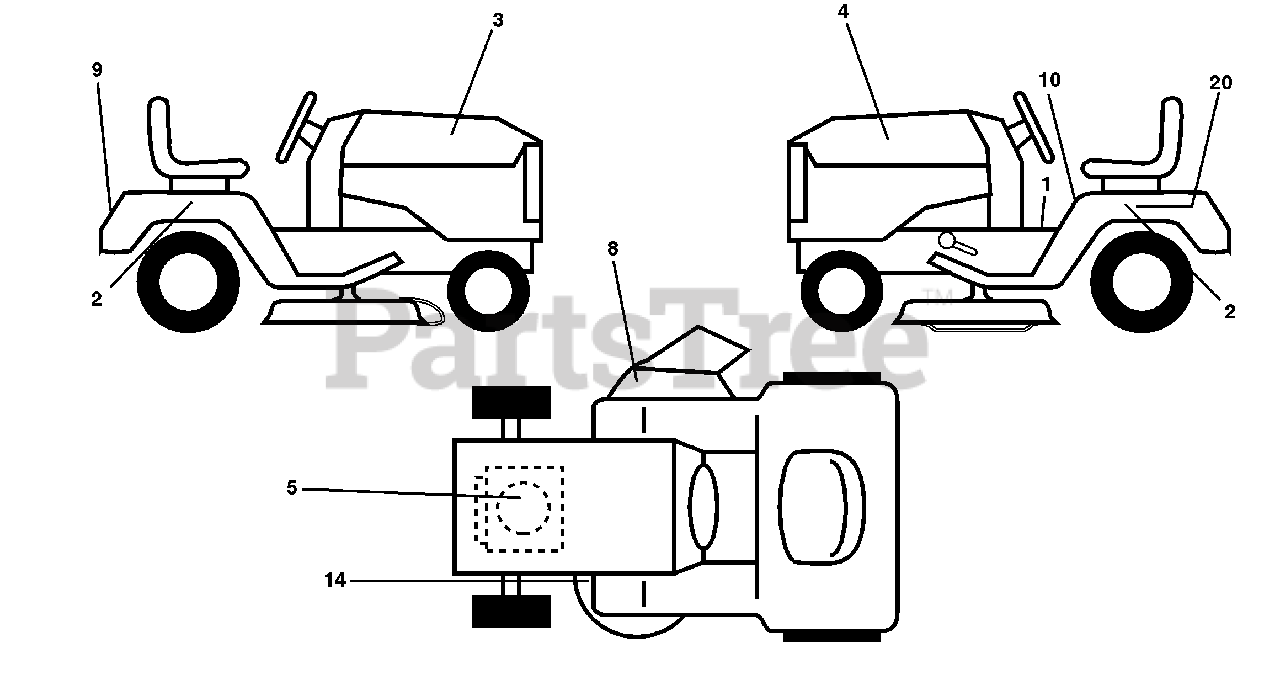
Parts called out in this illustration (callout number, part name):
1	Decal Oper. Step Thru Eng/Fr
2	Decal Fender Auto Husq Radius
3	Decal Hood LH
4	Decal Hood RH
5	Decal HP Engine
8	Decal Warning
9	Decal Fender Husq
10	Decal Fender Danger Eng/Fr
14	Decal V-Belt Schematic
20	Decal Bat Dan/Psn
MK380	Mulcher Kit with Blades
